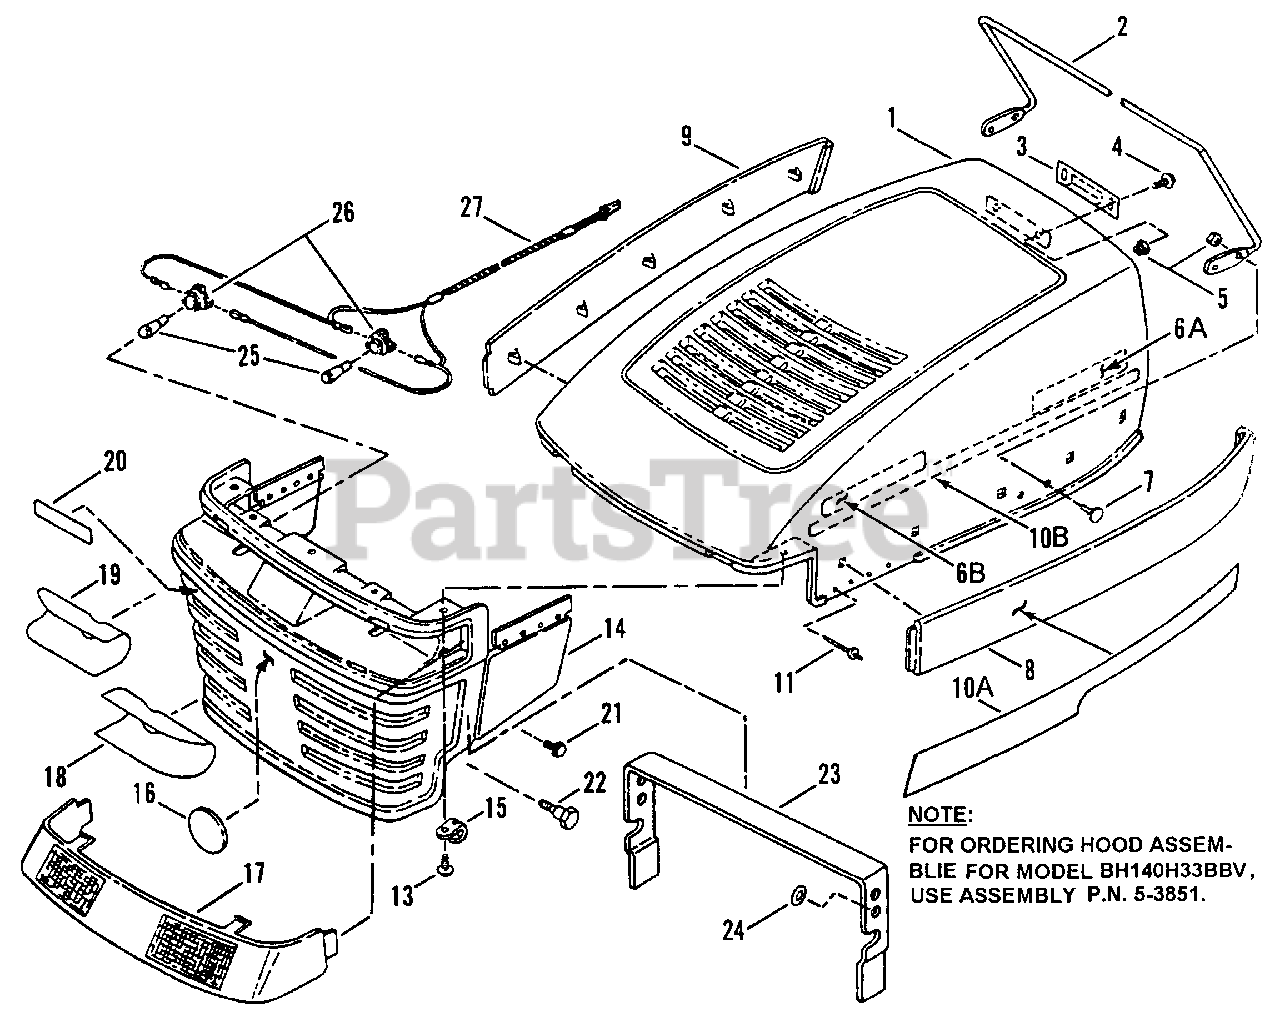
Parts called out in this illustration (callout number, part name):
1	HOOD, Mozart
2	ROD, Hood Support
3	LATCH, Spring
4	SCREW, 1/4-20 x 5/8" Truss Head, Torx
5	NUT, 1/4-20 Hex Nyloc
6	LOGO - BLACKHAWK
7	BOLT, 1/4-20 x 5/8" Flat Head Carriage
8	PANEL, Hood (Left Hand) (Black)
9	PANEL, Hood (Right Hand) (Black)
10A	DECAL, Hood (Right Hand) (Hydro Drive)
10A	DECAL, Hood (Left Hand) (Hydro Drive)
10B	DECAL, Hood (Right Side)
10B	DECAL, Hood (Left Side Shown)
11	RIVET, 1/8" Pop
13	SCREW, M4.8 x 1.59 x 16.00MM, Special
14	GRILLE, Hood
15	CLIP, "J"
16	DECAL, Molded Medallion
17	LENS, Grille (Headlights)
18	DECAL, Reflect (Left Hand)
19	DECAL, Reflect (Right Hand)
20	DECAL - SNAPPER, 4" Molded Logo (Silver Letters - Blue Stripe)
21	SCREW, 5/16-18 x 1/2" Self-Tapping
22	BOLT, Shoulder, 3/8-16 x 1 1/4" Hex Socket, Torx
23	BRACE, Hood Support
24	RETAINER, Bolt
25	BULB, Headlights
26	SOCKET, Headlight Bulb
27	HARNESS, Headlight Wiring
